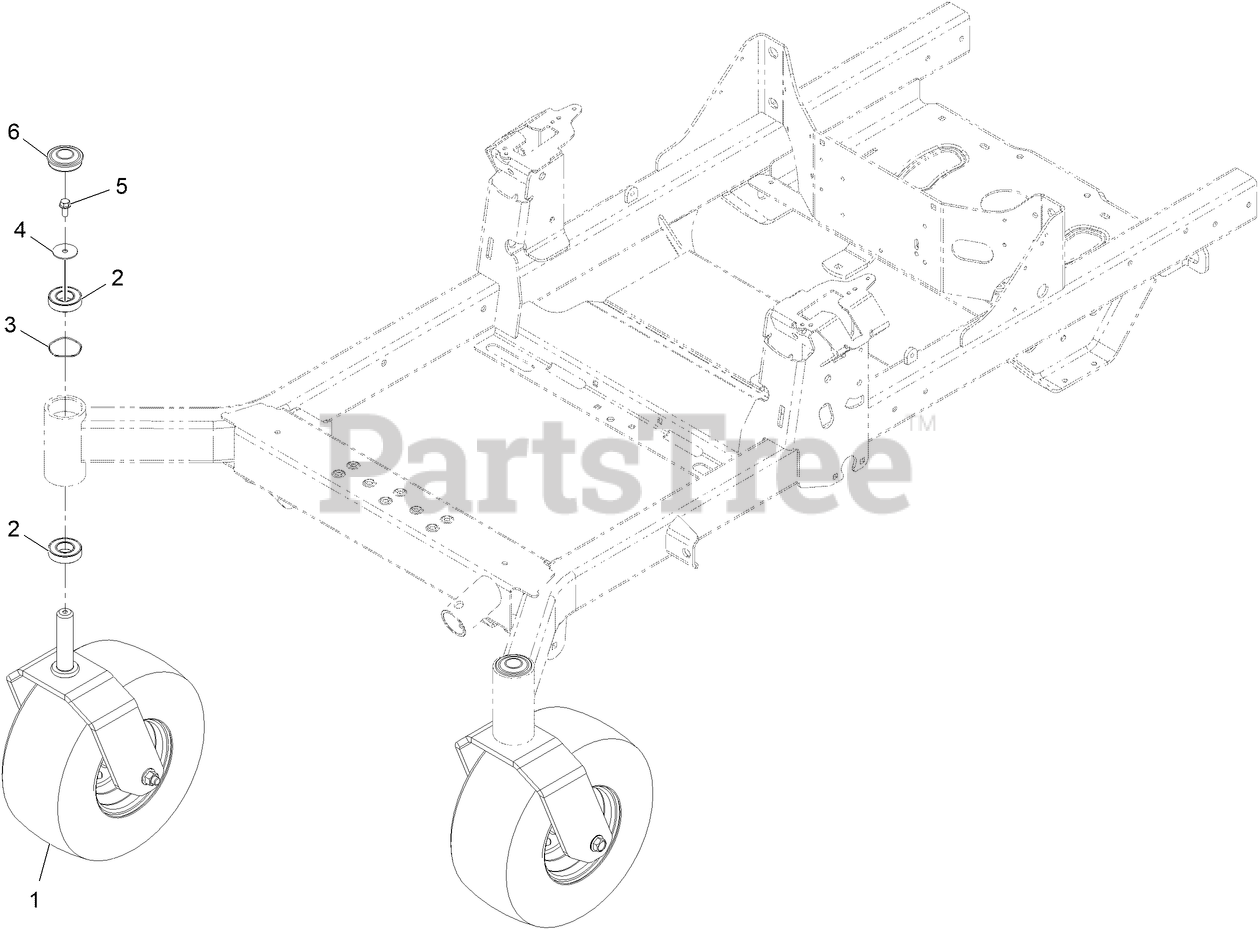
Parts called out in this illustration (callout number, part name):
1	ASM-Front Caster W/Fork
2	BEARING-BALL
4	WASHER-FLAT
5	SCREW-HHF
6	CAP, GREASE
